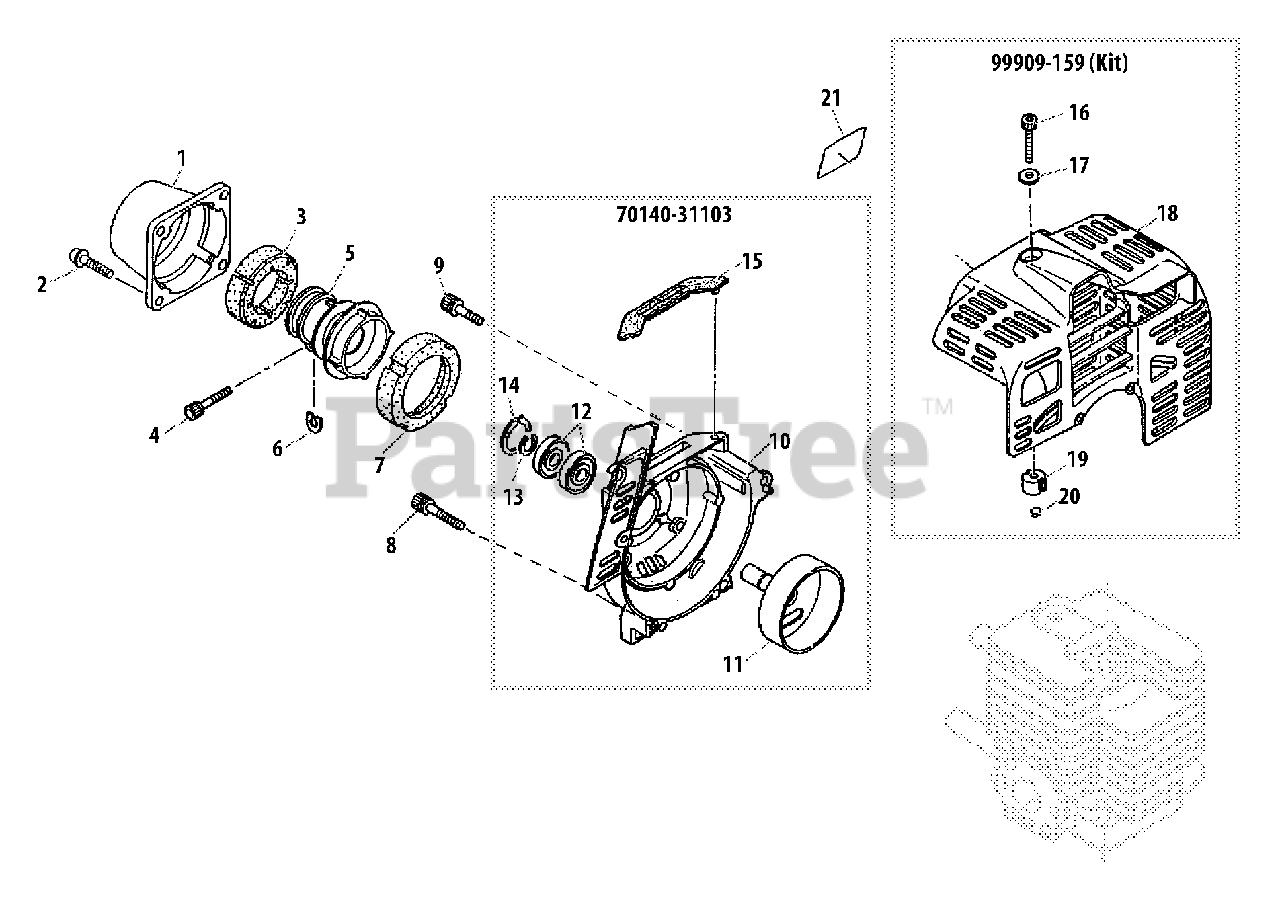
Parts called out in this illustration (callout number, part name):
1	CAP
2	SCREW - 5X16
3	CUSHION - FRONT
4	SCREW - 5X25
5	CLAMP, MAIN PIPE
6	SHIM
7	CUSHION - REAR
8	SCREW - 5X35
9	SCREW - 5X16
10	CASE, FAN
11	DRUM, CLUTCH
12	BEARING, BALL - 6000
13	RING, RETAINING
14	RING, RETAINING - 26
15	CUSHION
16	SCREW - 5X25
17	WASHER - 5
18	COVER, ENGINE - RED
19	INSULATOR
20	CLIP
21	LABEL - MODEL
70140-31103	FAN CASE ASSY
99909-159	DIAPHRAGM/GASKET KIT
